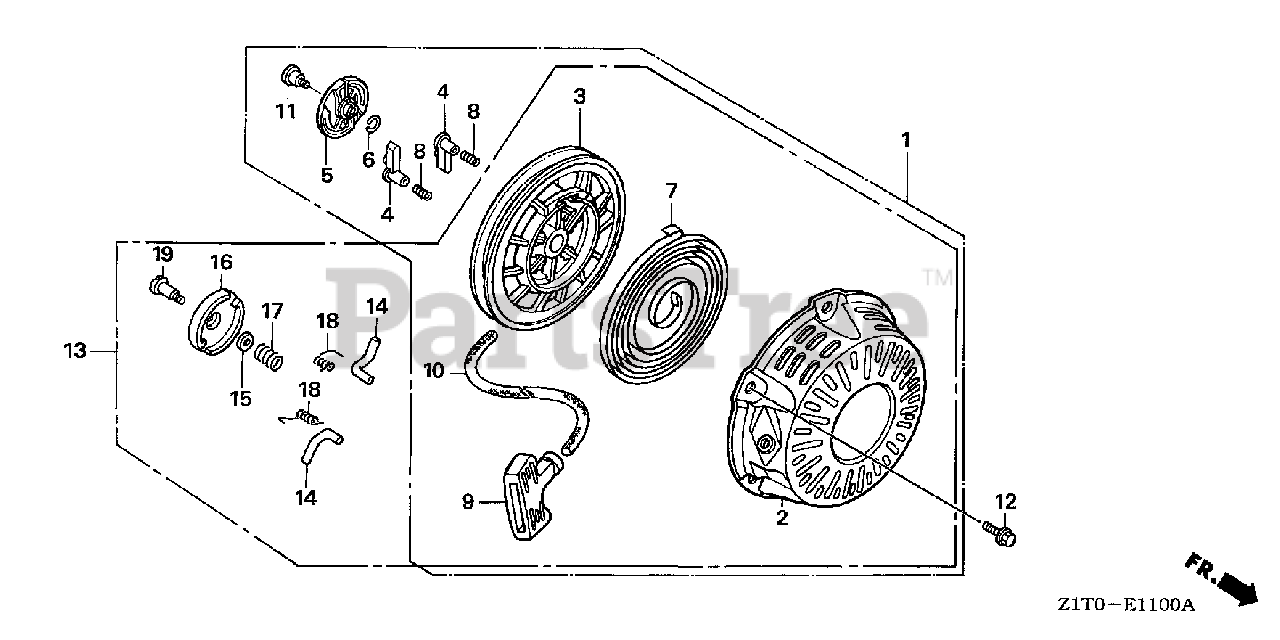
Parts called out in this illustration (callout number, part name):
1	STARTER ASSY., RECOIL *R280* (POWER RED)
1	STARTER ASSY., RECOIL *NH1* (BLACK)
2	CASE, RECOIL STARTER *R280* (POWER RED)
2	CASE, RECOIL STARTER *NH1* (BLACK)
3	REEL, RECOIL STARTER (NATURAL)
3	REEL, RECOIL STARTER (BLACK)
4	RATCHET, STARTER
5	GUIDE, RATCHET
6	SPRING, FRICTION
7	SPRING, RECOIL STARTER
8	SPRING, RETURN
9	GRIP, STARTER
10	ROPE, RECOIL STARTER
11	SCREW, SETTING
12	BOLT, FLANGE (6X10)
13	STARTER ASSY., RECOIL *R280* (POWER RED)
13	STARTER ASSY., RECOIL *NH1* (BLACK)
14	RATCHET, STARTER
15	PLATE, FRICTION
16	GUIDE, RATCHET
17	SPRING, FRICTION
18	SPRING, RETURN
19	SCREW, SETTING
